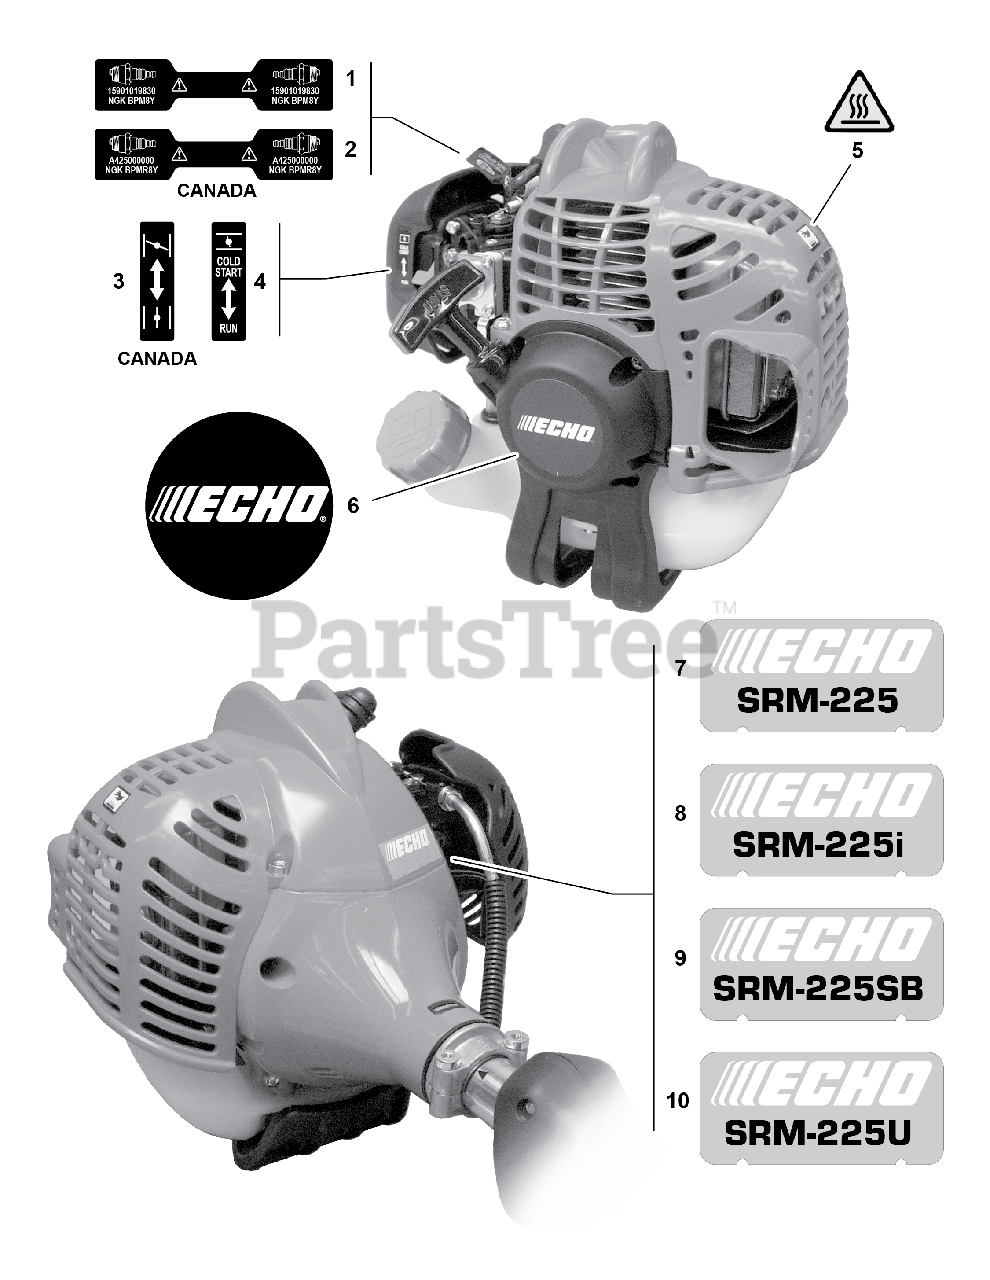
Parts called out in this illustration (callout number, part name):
1	LABEL - SPARK PLUG -- BPM-8Y
2	LABEL - SPARK PLUG -- BPMR-8Y
3	LABEL - CHOKE
4	LABEL - CHOKE
5	LABEL - HOT SURFACE
6	LABEL - ECHO
7	LABEL - MODEL -- SRM-225
8	LABEL - MODEL -- SRM-225i
9	LABEL - MODEL -- SRM-225SB
10	LABEL - MODEL -- SRM-225U
